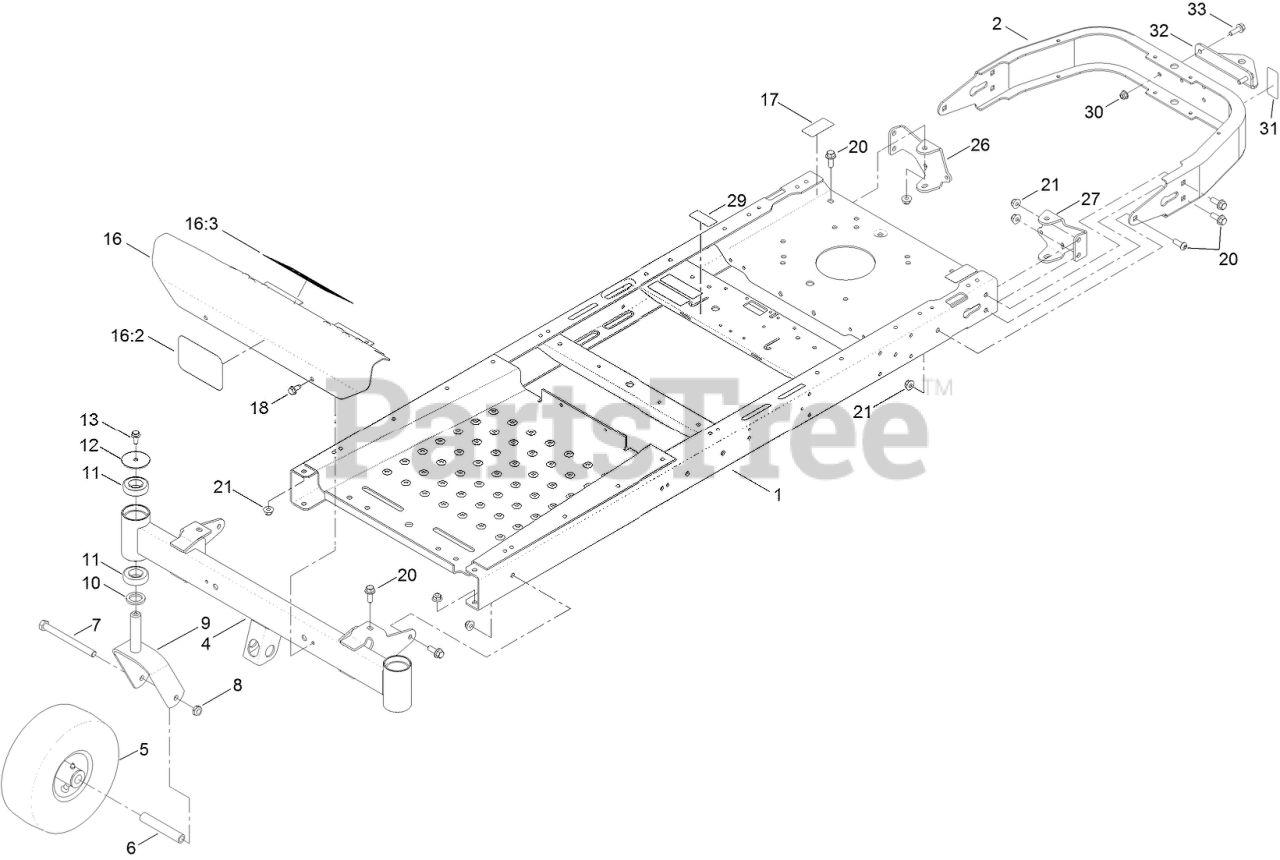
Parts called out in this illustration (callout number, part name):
2	BUMPER-REAR
4	AXLE-FRONT
5	Caster Wheel ASM
6	BUSHING-SPANNER
7	SCREW-HH
8	NUT-LOCK, NI
9	CASTER FORK ASM
10	WASHER-THRUST
11	BEARING-BALL
12	WASHER
13	SCREW-HHF
16	FOOTREST ASM
16:3	DECAL-DANGER
17	DECAL-BYPASS
18	SCREW-HWHTF
20	SCREW-HHF
21	NUT-HF, NI
26	MOUNT-HYDRO, REAR (RH)
27	MOUNT-HYDRO, REAR (LH)
29	DECAL-LOCATION, SERVICE DEALER
30	NUT-HF, NI
32	BRACKET-HITCH
33	SCREW-HHF
